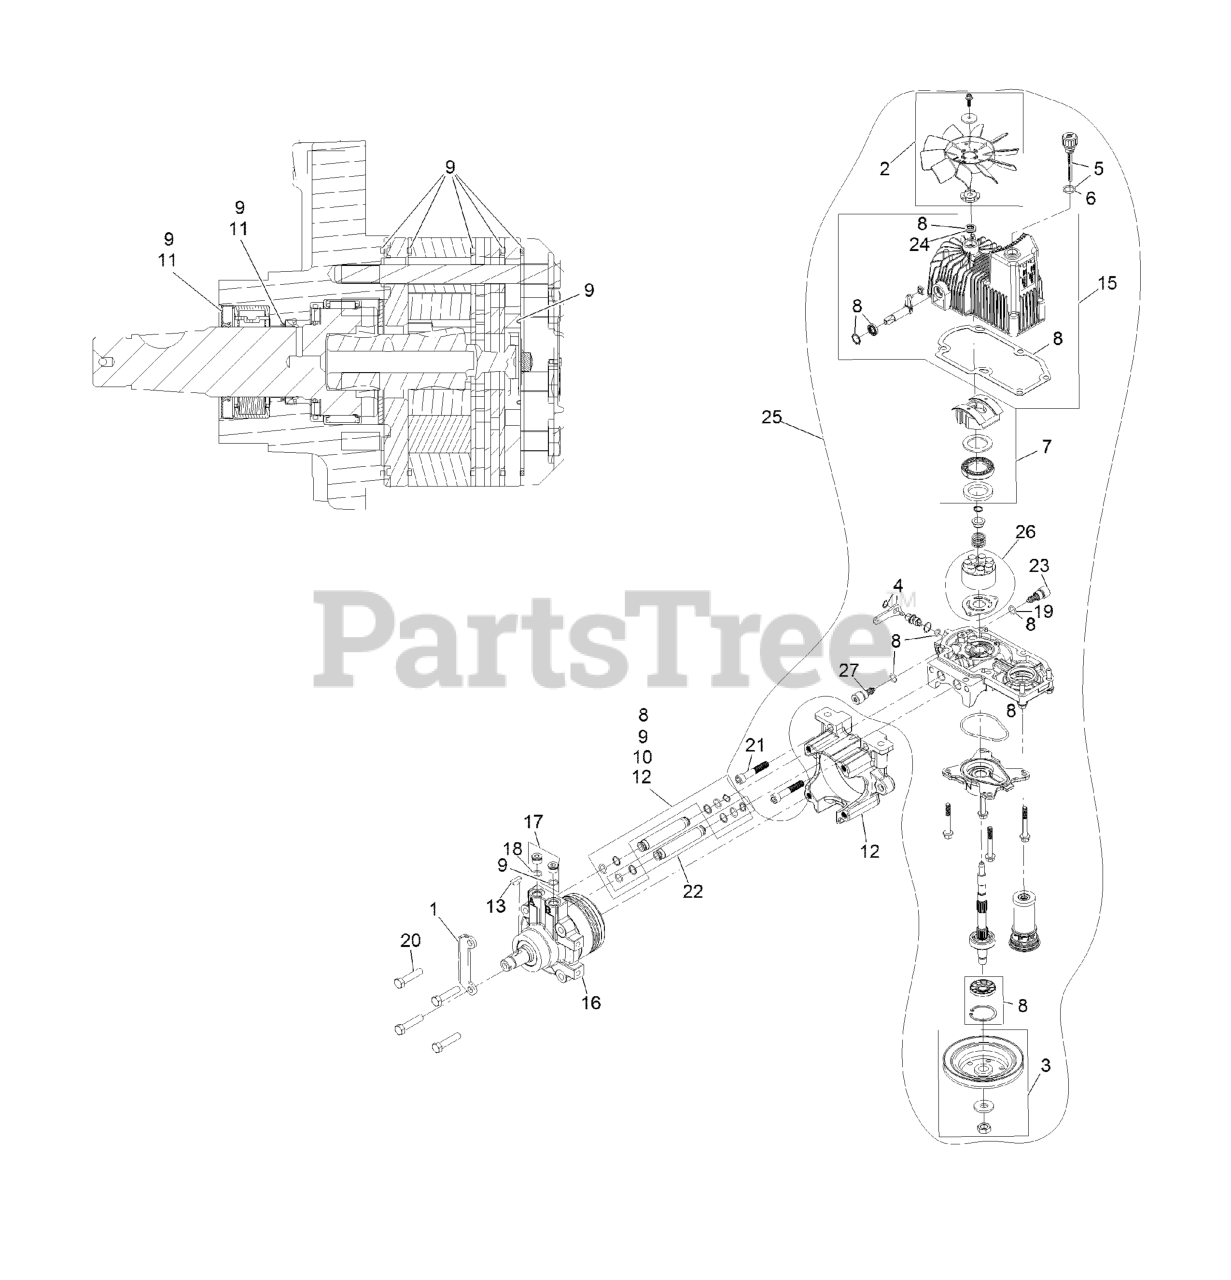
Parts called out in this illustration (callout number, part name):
1	Plate, Horse Shoe Mount
2	Kit, 7.8 In Fan
3	PULLEY KIT
4	HANDLE-BYPASS VALVE, HYDRO
5	DIPSTICK-HYDRO W/GASKET
6	GASKET-DIPSTICK, HYDRO
7	SWASH BLOCK KIT
8	Kit, Pump Seal
9	MOTOR SEAL KIT
10	TUBE SEAL KIT
11	OUTPUT SHAFT SEAL KIT
12	NOSE CUP-UHT
13	KEY-WOODRUFF
15	Kit, Housing-Hydro LH
16	KIT, MOTOR TG310CC LH
17	MAGNETIC PLUGS SERVICE KIT
19	O-RING-CHECK VALVE
20	SCREW HH
21	SCREW-HSH
22	HYDRAULIC TUBE KIT
23	SHOCK VALVE, 12CC HYDRO
24	SEAL-FAN DRIVE
25	Kit, Pump Section 16Cc LH
26	Kit - 16Cc Port Plate,Rotate Grp
27	Shock Valve Orificed 3800
